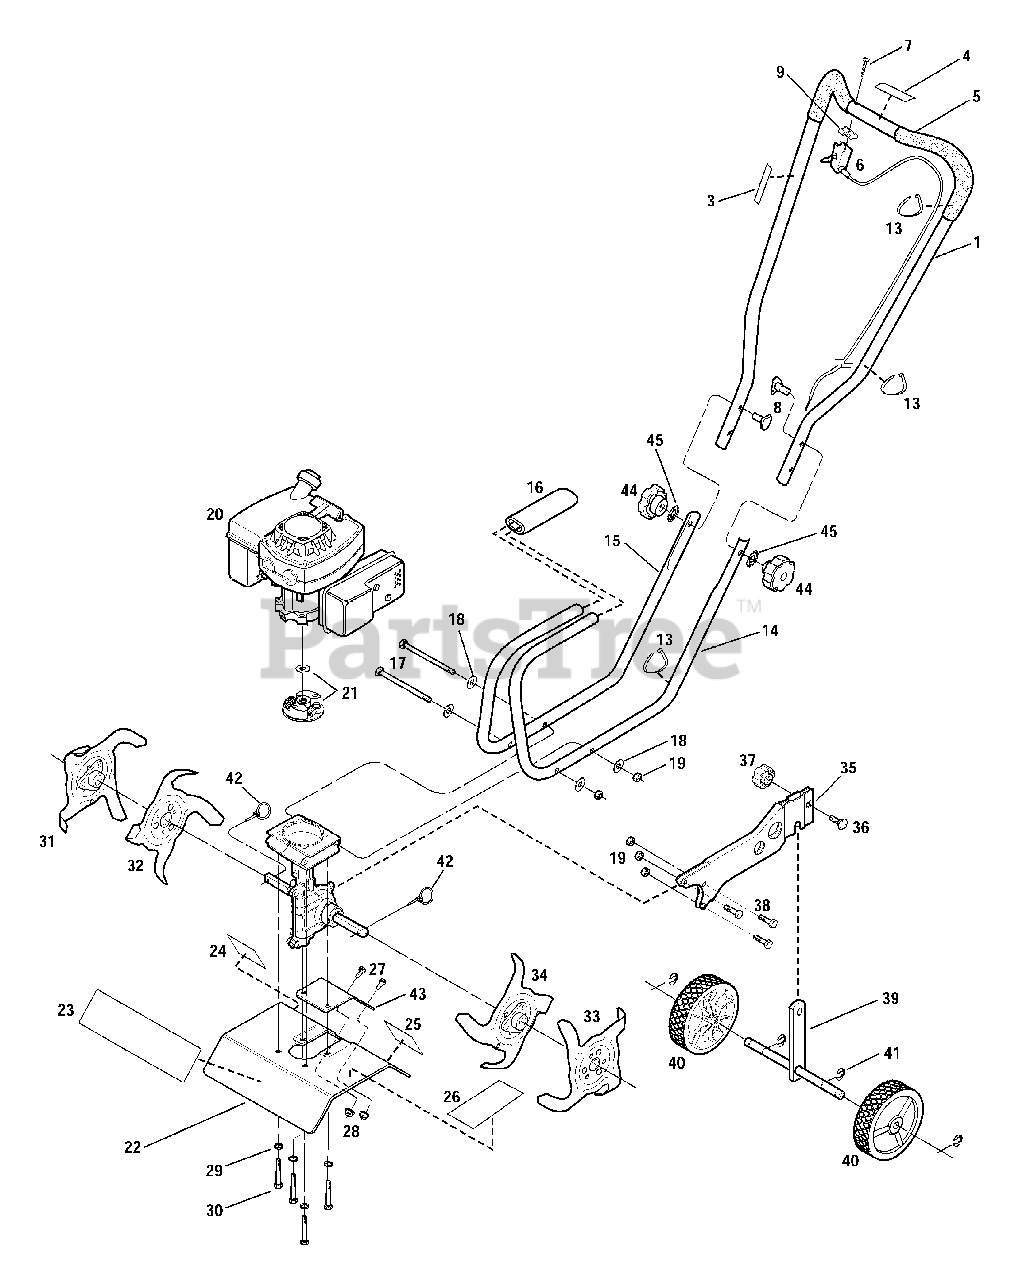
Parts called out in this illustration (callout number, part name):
1	Handlebar Ass'y.
3	Decal - Starting Stabilization
4	Decal - Throttle/Tines Lever Operation
5	Handlebar Grip, PVC
6	Throttle/Tines Lever and Cable
7	Pan Hd. Screw, #10-16 x 1-1/2
8	Saddle Hd. Screw, 5/16-18 x 2
9	Spacer, Throttle/Tines Lever
13	Plastic Wire Tie
14	Lower Handlebar - Left-Side
15	Lower Handlebar - Right-Side
16	Foam Sleeve
17	Hex Hd. Screw, 1/4-20 x 5
18	Flat Washer, 1/4-20
19	Hex Locknut, 1/4-20
20	Engine
21	Clutch Rotor and Washer
22	Tine Shield
23	Decal - Logo
24	Decal - Warning, Rotating TInes
25	Decal - Warning, Hot Surfaces
26	Decal - Caution, Operation Hazards
27	Hex Hd. Screw, #10-24 x 1/2
28	Flange Locknut, #10-24
29	Lock Washer, 1/4-20
30	Hex Cap Screw, 1/4-20 x 2
31	Outer Tine - Right-Hand Side
32	Inner Tine - Right-Hand Side
33	Outer Tine - Left-Hand Side
34	Inner Tine - Left-Hand Side
35	Wheel Bracket
36	Carriage Bolt
38	Hex Hd. Screw, 1/4-20 x 1
40	Wheel
41	E-Ring
42	Ring Lock Pin
43	Tine Hood Cover
45	Lock Washer, 5/16
